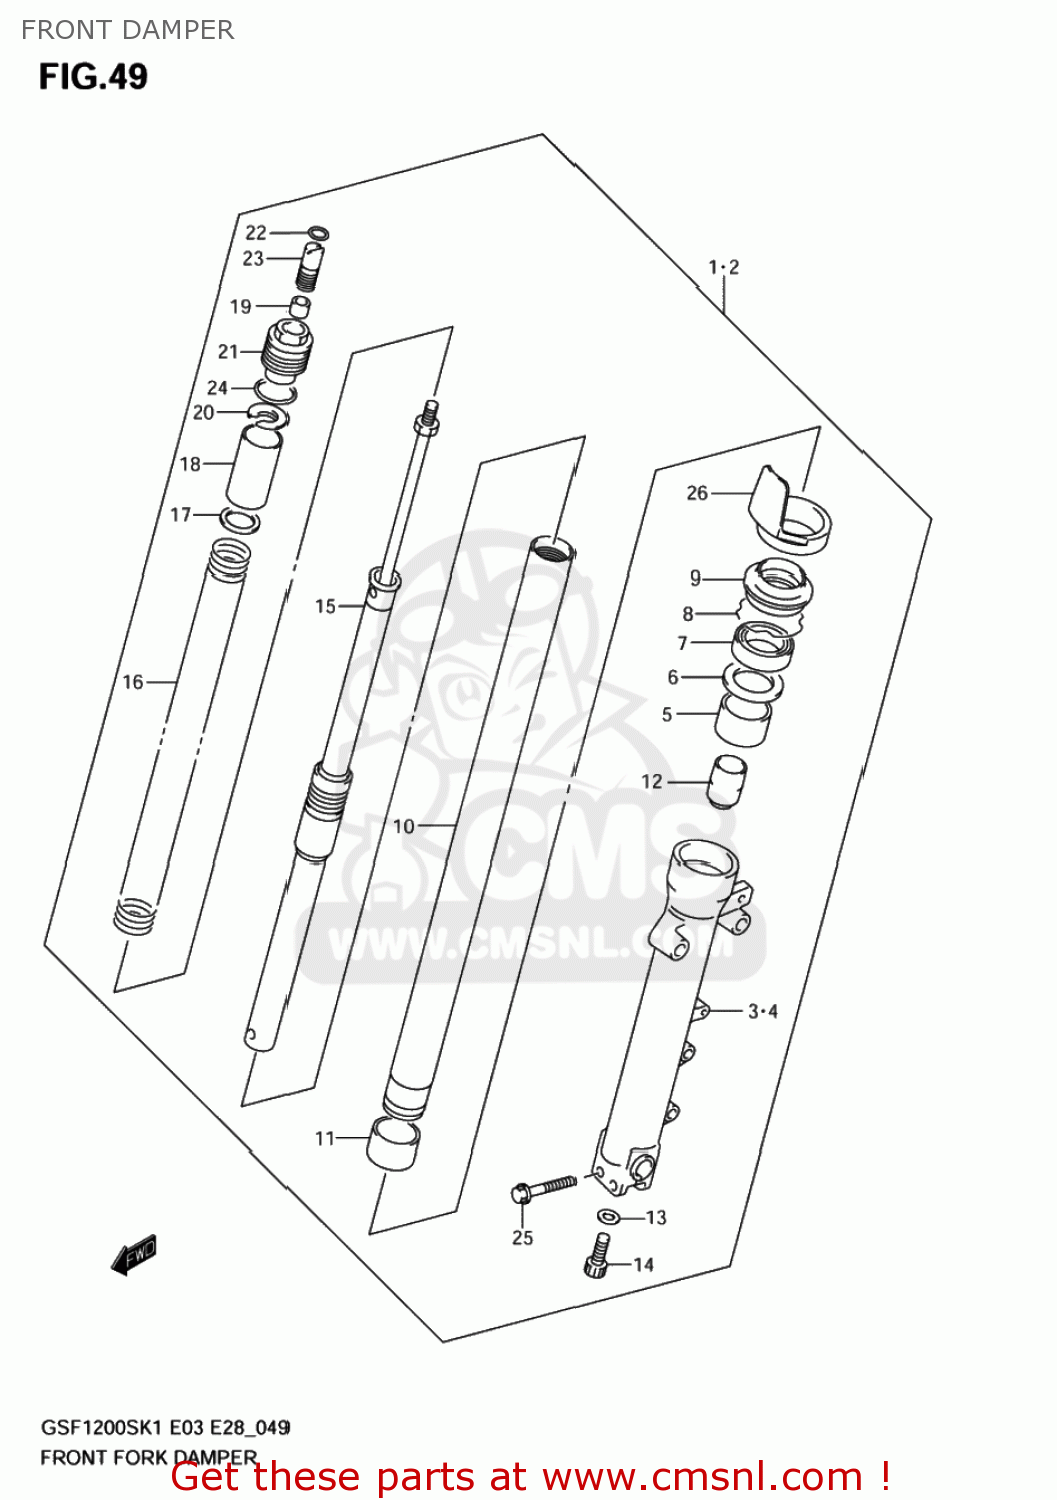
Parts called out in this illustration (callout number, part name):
1	DAMPER ASSY,FR FORK,R
2	DAMPER ASSY,FR FORK,L
3	TUBE,OUTER,R
4	TUBE,OUTER,L
5	BUSH,GUIDE
6	SPACER,SEAL
7	SEAL,OIL
8	CIRCLIP,FORK OIL SEAL
9	SEAL,DUST
10	TUBE,INNER
11	BUSH,SLIDE
12	PIECE,OIL LOCK
13	GASKET (NAS)
14	BOLT(8X27)
15	ROD,FR DAMPER
16	SPRING,FR
17	SEAT,SPRING LWR
18	COLLAR,SPRING(32.9X34X50)
19	NUT
20	SEAT,SPRING UPR
21	BOLT,FORK
22	O RING(D:2.5,ID:13.8)
23	ADJUSTER,SPRING
24	O RING
25	BOLT
26	PROTECTOR
